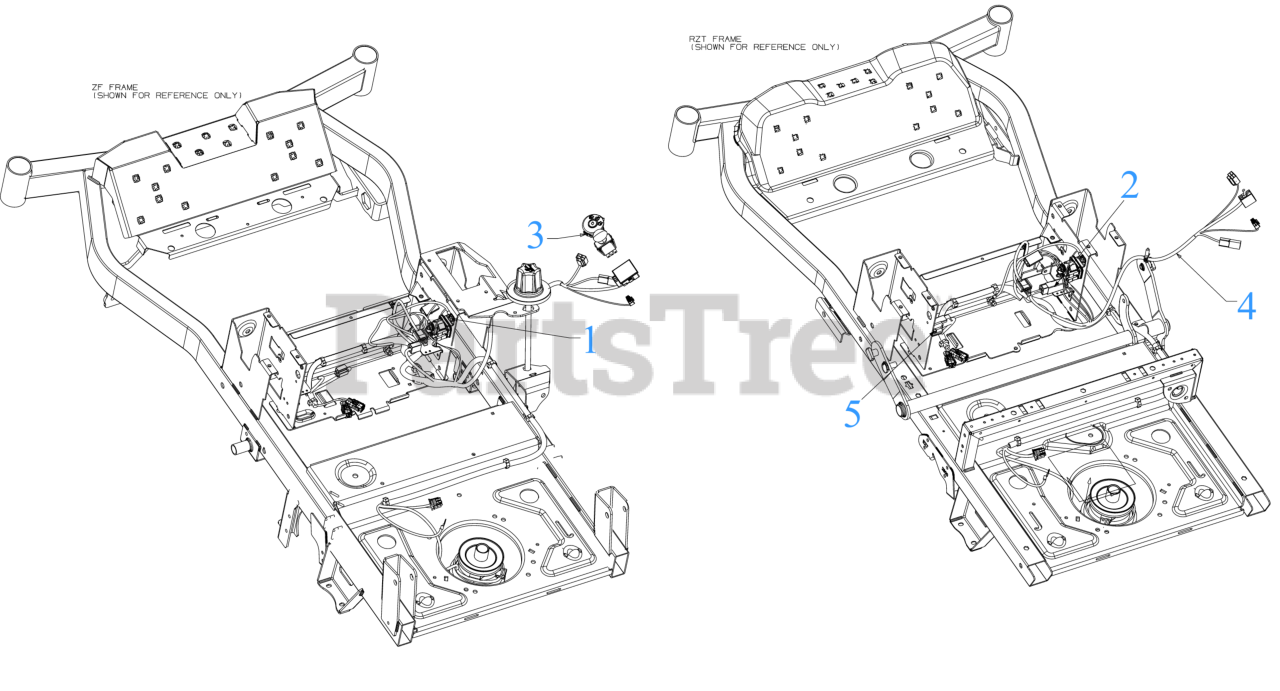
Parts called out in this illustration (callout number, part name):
1	SCREW 1/4-20X.625
2	INTERLOCK SWITCH (NO/NC)
3	KEY SWITCH (3 POS 6 PIN)
4	HARNESS (EPTO/HM/SOL/AGM)
4	12V SOLENOID
4	MAIN HARNESS
5	SHOULDER SCREW
